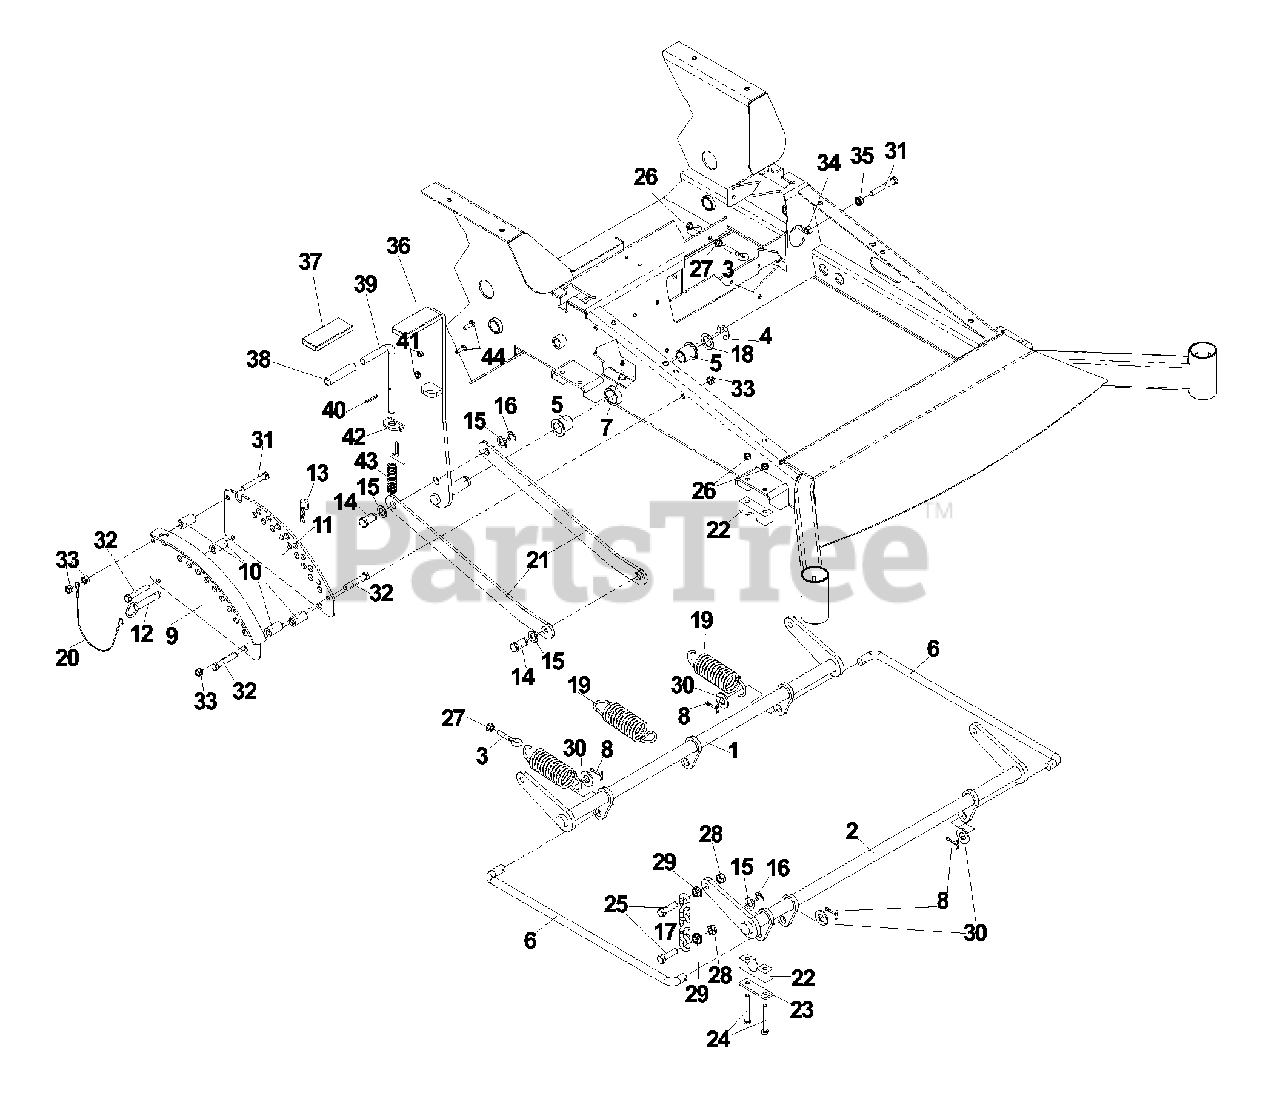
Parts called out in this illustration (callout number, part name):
1	Shaft, lift, rear
2	Shaft, lift, front
3	Eyebolt, right
4	E-ring, 7/8
5	Bushing, flanged-PM
6	Link, connecting
7	Zerk, long
8	Pin, cotter, 5/32 x 1 1/4
9	Adjustment plate
11	Adjustment plate
13	Hairpin, #4
14	Pin, clevis
15	Bushing, machine, 5/8
16	E-ring, 5/8
17	Lift chain
18	Bushing, machine, 7/8
19	Spring, extension
21	Lift linkage
22	Pillow block
23	Bar, reinforcement
24	Bolt, 5/16-18 x 2 1/2
25	Bolt, 7/16-14 x 1 1/2
26	Nut, 5/16-18, centerlock
27	Nut, 5/16-18, serrated washer
28	Nut, 7/16-14, centerlock
29	Nut, 7/16-14, whiz
30	Washer, 5/8
31	Bolt, 3/8-16 x 2 1/2
32	Bolt, 3/8-16 x 2 1/4
33	Nut, 3/8-16, centerlock
34	Nut, 3/8-16, nyloc
35	Nut, 3/8-16, serrated washer
40	Pin, 3/16 x 1 1/4, grooved
41	Nut, 1/4-20, centerlock
42	Pin mt, upper
44	Bolt, 1/4-20 x 3/4
